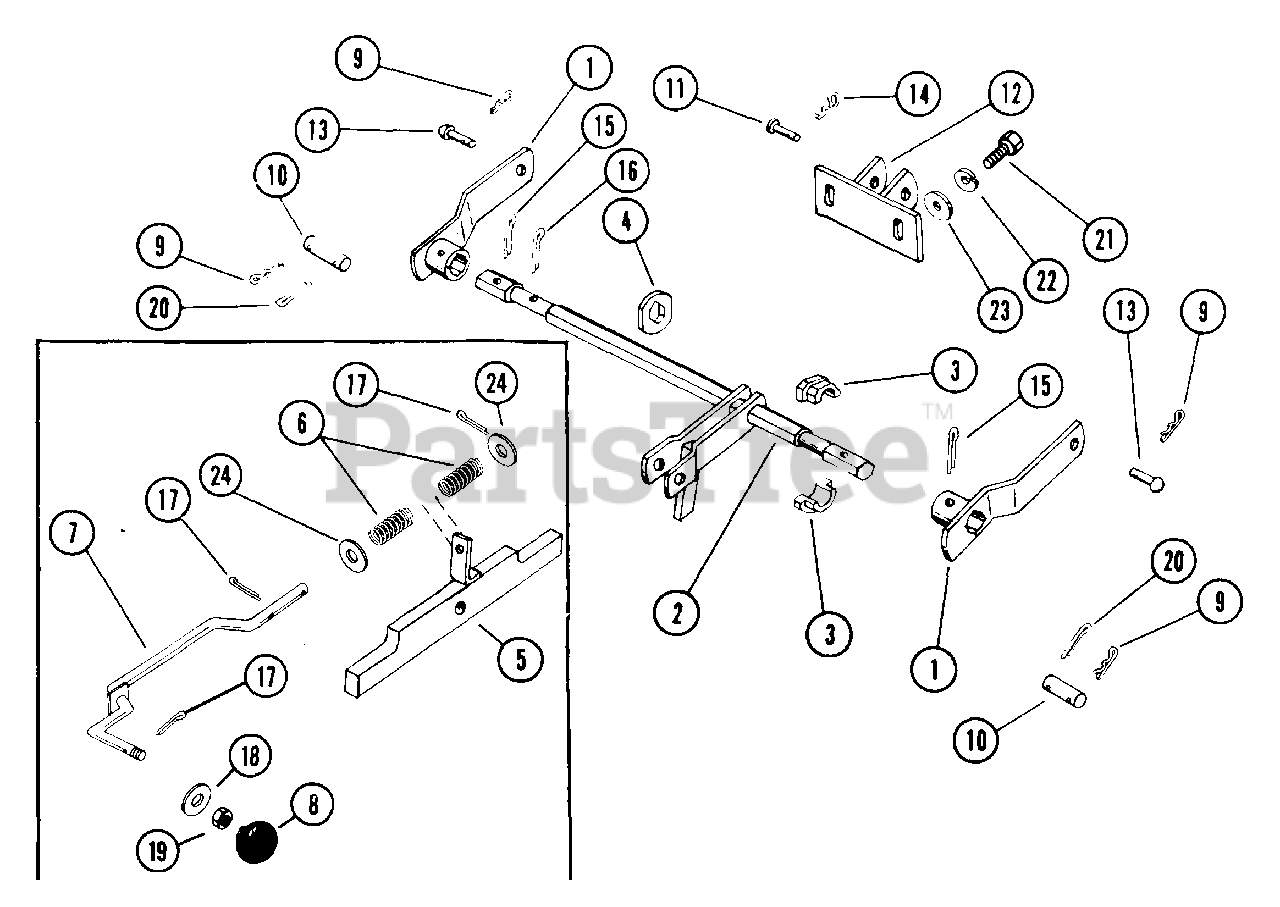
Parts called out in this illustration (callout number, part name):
2	REAR ROCK SHAFT
3	BSHG-FLG 1.000X1.750X1.000
6	SG-COMP .65X.56X1.50
7	LATCH ROD
8	KNOB-STEERING LOCK
9	PIN-HAIR INT .14X.4X2.75
11	PIN-CLEV .619X2.0 YWZC
13	PIN-CLEV .50X1.25 RH ST PL
14	PIN-HAIR INT .09X.188 PL
15	PIN-COTR .18X2.0 ZCC
16	PIN-COTR .18X1.50 PL
17	PIN-COTR .12X.75 PL
18	WSHR-FL-STL .406X1.00X.062 PL
19	NUT-JAM .375-16 PL
20	PIN-COTR .12X1.0 PL
21	BLT-HEX .38-16X.75 PL GR2
22	WSHR-LK .375X.094 MED PL
23	WSHR-FL-STL .438X1.0X.083 PL
24	WSHR-FL-STL.406X.812X.065PL
